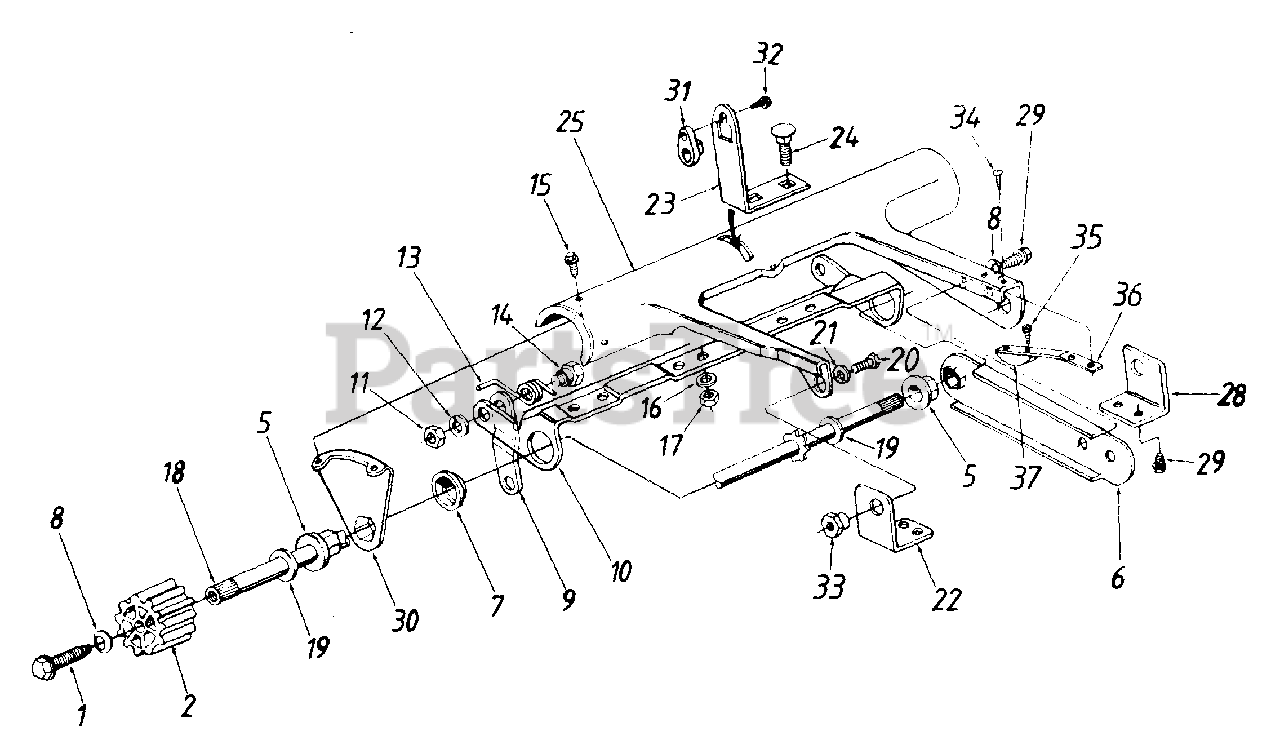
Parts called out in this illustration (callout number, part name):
1	Hex Scr. 1/4-20 x .75" Lg. (Gr. 5)
2	Wheel Drive Pinion
5	Hex Flange Brg..504" I.D.
8	Bell-Wash..265" I.0. x .75" O.D.
11	Hex Nut 5 16-18 Thd.
12	L-Wash. 5/16" l.D.
13	Torsion Spring - R.H.
14	Shoulder Bolt .437" Dia.
15	Hex L-Hd. AB-Tap Scr. 1/4" x .62" Lg.
16	L-Wash. 1/4" I.D.
17	Hex Nut 1/4-20 Thd.
18	Drive Shaft Ass'y.
19	Fl-Wash..531" I.D. x.93" O.D.
20	Hex Bolt 3/8-16 x .5" Lg.
21	L-Wash. 3/8" I.D.
32	Hex B-Tap Scr. #10 x .44" Lg.
33	Shld. Nut .625" Dia. x .165" Lg.
34	Truss Mach. B-Tap Scr.#10 x .5" Lg.
35	Hex B-Tap Scr. #10 x 3/8" Lg.
36	Cantilever Spring
37	Chain Tensioner
